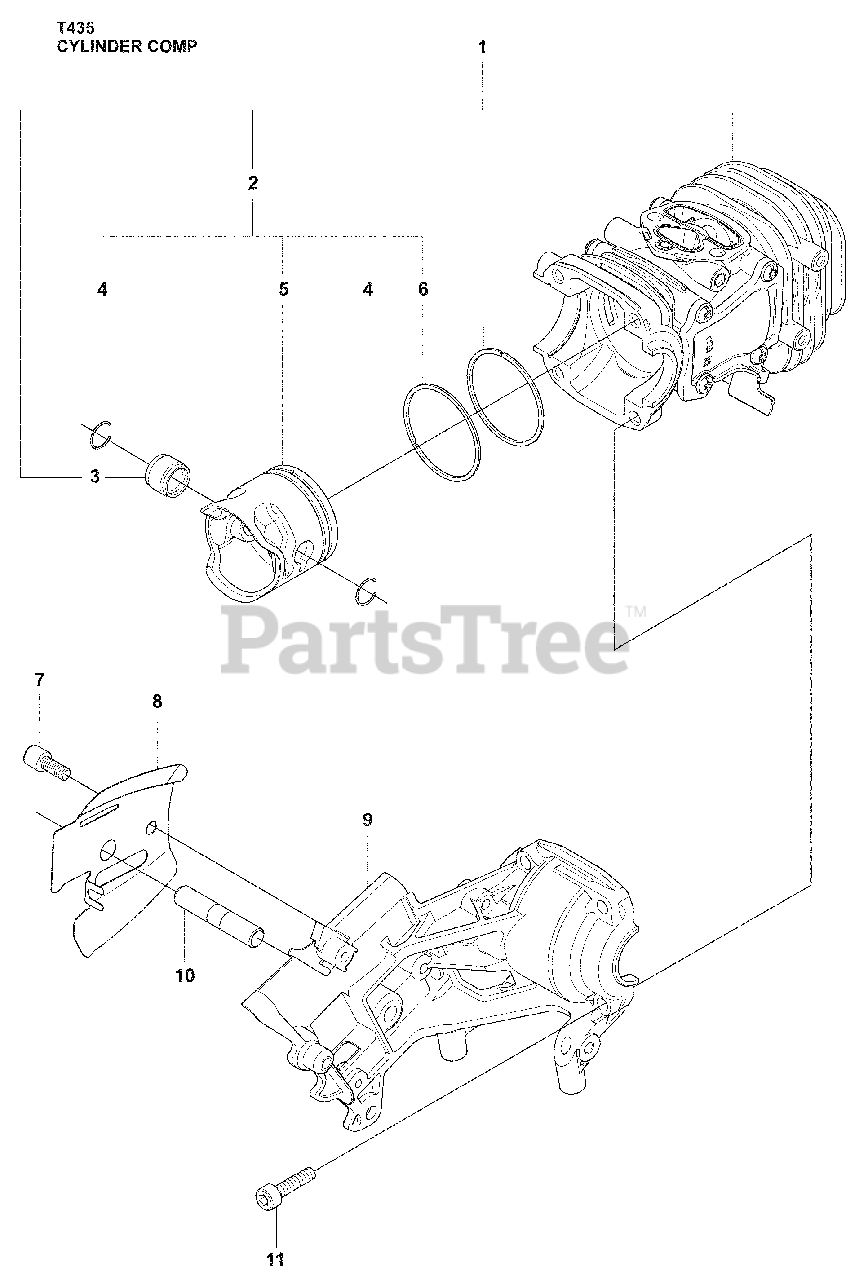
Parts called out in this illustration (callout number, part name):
1	Cylinder, compl.
2	Piston, compl.
3	Needle bearing
6	Piston ring
9	Crankcase
11	Bolt
